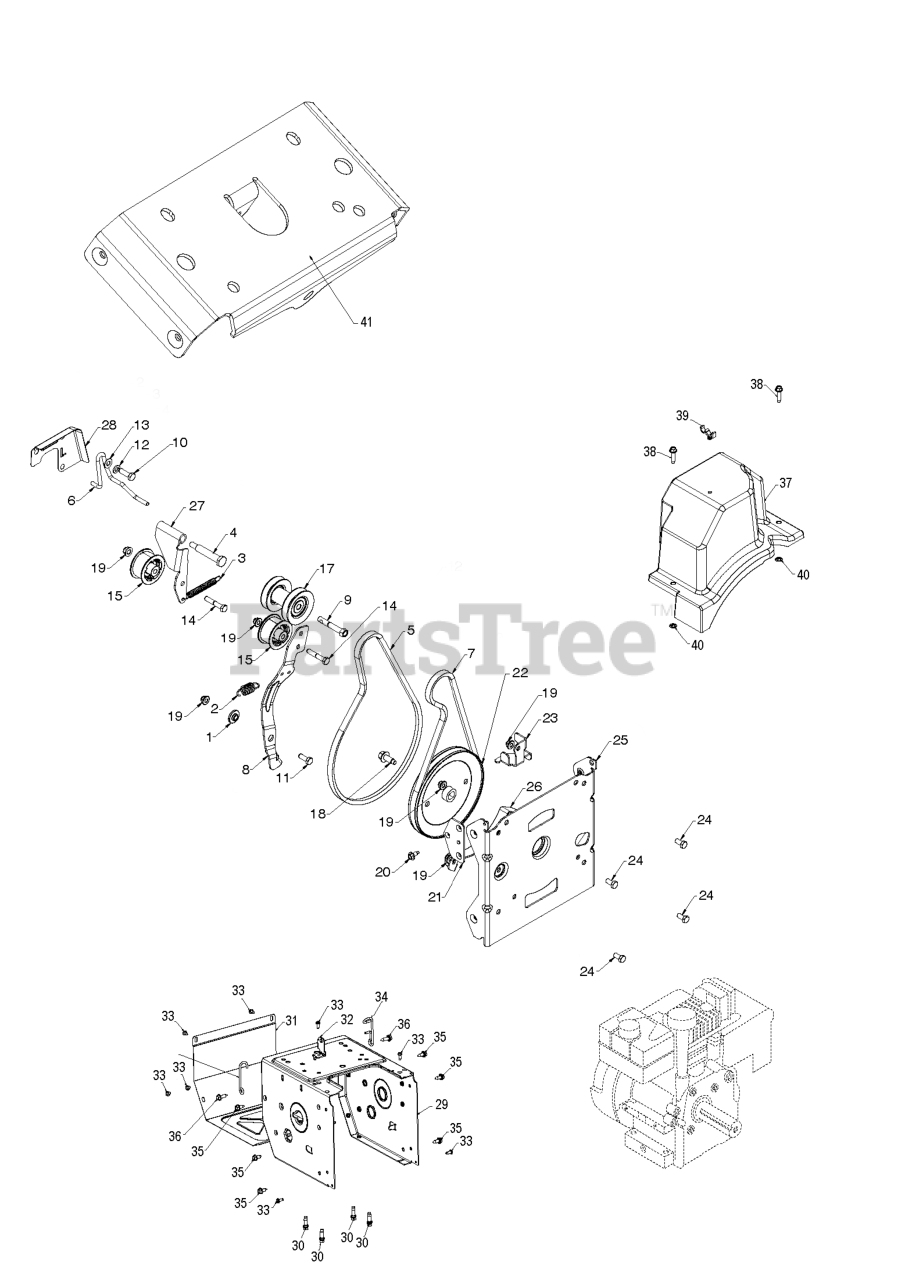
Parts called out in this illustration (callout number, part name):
1	BUSHING.BRAKE.ARM
2	SPRING RETURN, IDLER ARM, IMPE
3	SPRING RETURN IDLER ARM
4	BOLT 5/16-24X2.25 HEX HEAD SHO
6	Belt Keepers
7	LOW CRANK IMPELLER BELT
8	ARM.IDLER.AUTO-PH.676
9	BOLT.ENGINE.PULLEY
11	BOLT HEXAGON BOLT 5/16-18 X 7/
12	WASHER SPRING LOCK WASHER WITH
13	WASHER 11/32 X 11/16 X 14 GA T
14	BOLT, HEX 5/16-18X1-3/4
15	PULLEYIDLER.2.0.W/SPACER.CZ
18	SCREW HEXAGON HEAD FLANGE 3/8-
19	NUT HEXAGON FLANGE 5/16-18 ST
20	HEX.WASHER.HEAD 1/4-20 X .65
21	BRACKET NUT BLACK ZINC PLATE
22	PULLEY IMPELLER DD 4L
23	GUIDE.LOWER.AUGER.BELT.479
25	BRACKET.AUG.HOUSING.INTER.BLAC
26	BRACKET.BELT.KEEPER.LOWER.BLAC
27	ARM DRIVE IDLER CLEAR ZINC PLA
29	FRAME.GEAR.CASE.ORANGE
30	BOLT 3/8-16X1-1/8
31	COVER COVER.FRAME MS668 ORANGE
32	BRACKET.SHIFTER.BZP
33	SCREW.HEX HEAD W/COLLAR 1/4-20
34	WIREFORM.SUPPORT.CABLE
35	BOLT.HEX.HD.WASHER.5/16-18X.75
36	SCREW HEXAGON HEAD WITH COLLAR
37	COVER BELT ASM. LOW CRANK
38	SCREW HEX WASH THDRL BLK 1_4-
40	PALNUT 1/4
41	BRACKET.FRAME.SUPPORT.BLACK
